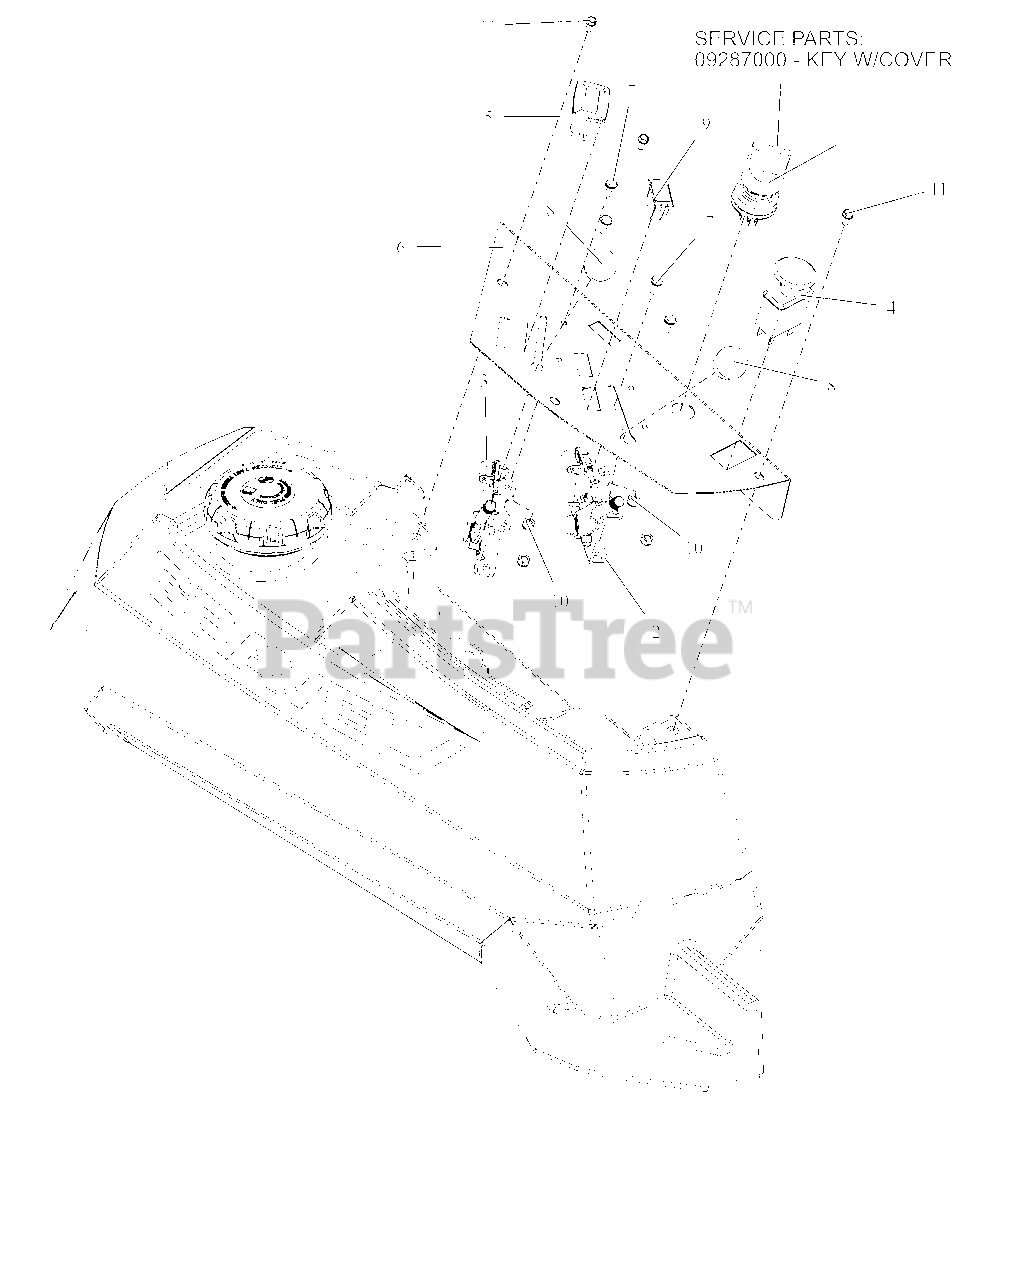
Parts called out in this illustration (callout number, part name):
1	SWITCH, IGNITION
1	KEY, W/ SHIELD
2	CABLE, PRO-CONTROL 28.50
3	CABLE, PRO-CONTROL 31.50"
4	SWITCH, CLUTCH
5	METER, HOUR W/MAINTENANCE
6	PT CONTROL PANEL - RED
7	@SCR-MCH 10-24X.50 HWH YWZC
8	KNOB-CONTROL-BLACK .38-16X.50
9	SWITCH,BLANK
10	@NUT-LK-NYL 10-24 W/INSRT YWZC
11	SCR-MCH 10-24X.38 HWHSTAINLESS
